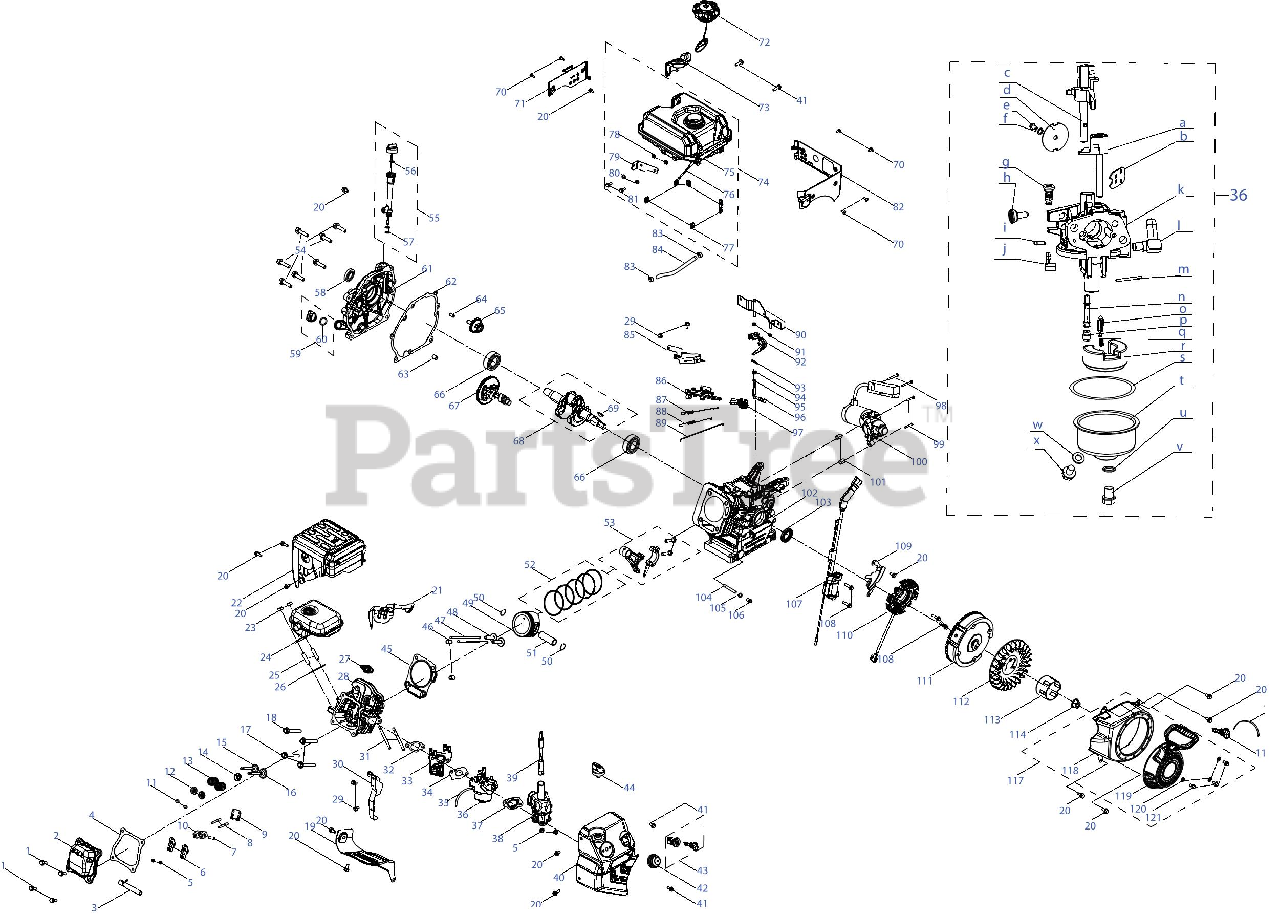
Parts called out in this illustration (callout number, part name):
1	Bolt, M6x16
2	Valve Cover
3	Breather Hose
4	Gasket, Valve Cover
5	Nut, M6
6	Rocker Arm Assembly
7	Rocker Arm Shaft
9	Rocker Arm Base
10	Rocker Arm Seat
11	Valve Adjust Cap, Exhaust
12	Valve Spring Seat
13	Valve Spring
14	Intake Valve Seal
15	Exhaust Valve
16	Intake Vavle
17	Bolt, M10x1.25x65
18	Bolt, M10x1.25x70
19	Shroud
20	Bolt, M6x12
21	Shroud
22	Muffler Guard
23	Nut, M8
24	Muffler
25	Stud, M8x34
26	Gasket, Muffler
27	Spark Plug
28	Cylinder Head
29	Bolt, M6x12
30	Snow Guard
31	Stud, M6x90
32	Gasket, Carburetor Insulator
33	Insulator
34	Gasket, Carburetor
35	Fuel Hose,3.2x6.5x170
36	Carburetor
37	Gasket, Air Filter
38	Heater Box
39	Choke Linkage
40	Control Panel
41	Bolt, M6x18
43	Stop Switch
44	Choke Lever
45	Gasket, Cylinder Head
46	Pin, 12x16
47	Push Rod
48	Tappet
49	Piston
50	Circlip
51	Piston Pin
52	Piston Ring Set
53	Connecting Rod Assembly
54	Bolt, M8x32
55	Dipstick
56	O-Ring, 21x2.77
57	O-Ring, 15.2x1.5
58	Oil Seal, 25x41.25x6
59	Oil Plug
60	O-Ring, 15.8x2.5
61	Crankcase Cover
62	Gasket, Crankcase
63	Pin, 9x14
64	Pin, 7x14
65	Governor Gear
66	Bearing, 6205
67	Camshaft
68	Crankshaft
69	Woodruff Key
70	Bolt, M5x14
71	Decorative Sheet, Right
72	Fuel Cap
73	Decorative Cover
74	Fuel Tank Assembly
75	Fuel Tank
76	Fuel Filter
77	Fuel Tank Mount Thread Tab
78	Nut, M6
79	Fuel Tank Mount Tab
80	Washer, 6.5x1.5x12
81	Bolt, M6x20
82	Decorative Sheet, Left
83	Clamp
84	Fuel Hose, 6.3x12.5x162
85	Governor Shield
86	Governor Gear Bracket Assembly
87	Governor Spring
88	Idle Spring
89	Throttle Linkage
90	Fuel Tank Bracket
91	Nut, M6
92	Governor Lever
93	Cotter Pin
94	Oil Seal, 6x11x4
95	O-Ring, 5.2x1.9
96	Governor Gear Shaft
97	Throttle Lever Knob
98	Screw, M4x48
99	Bolt, M6x32
100	Electric Starter
101	Pin, 8x8
102	Crankcase
103	Oil Seal, 25x41.25x6
104	Oil Drain Pipe
105	Washer, 10x1.5x16
106	Earth Bolt
107	Ignition Module
108	Bolt, M6x25
109	Lower Shield
110	Charging Coil
111	Flywheel
112	Cooling Fan
113	Starter Cup
114	Nut, M14x1.5
115	Tape, L=150mm
116	Stop Switch Key
117	Recoil Starter
118	Blower Housing
119	Recoil Starter
120	Washer, 6
121	Bolt, M6x10
